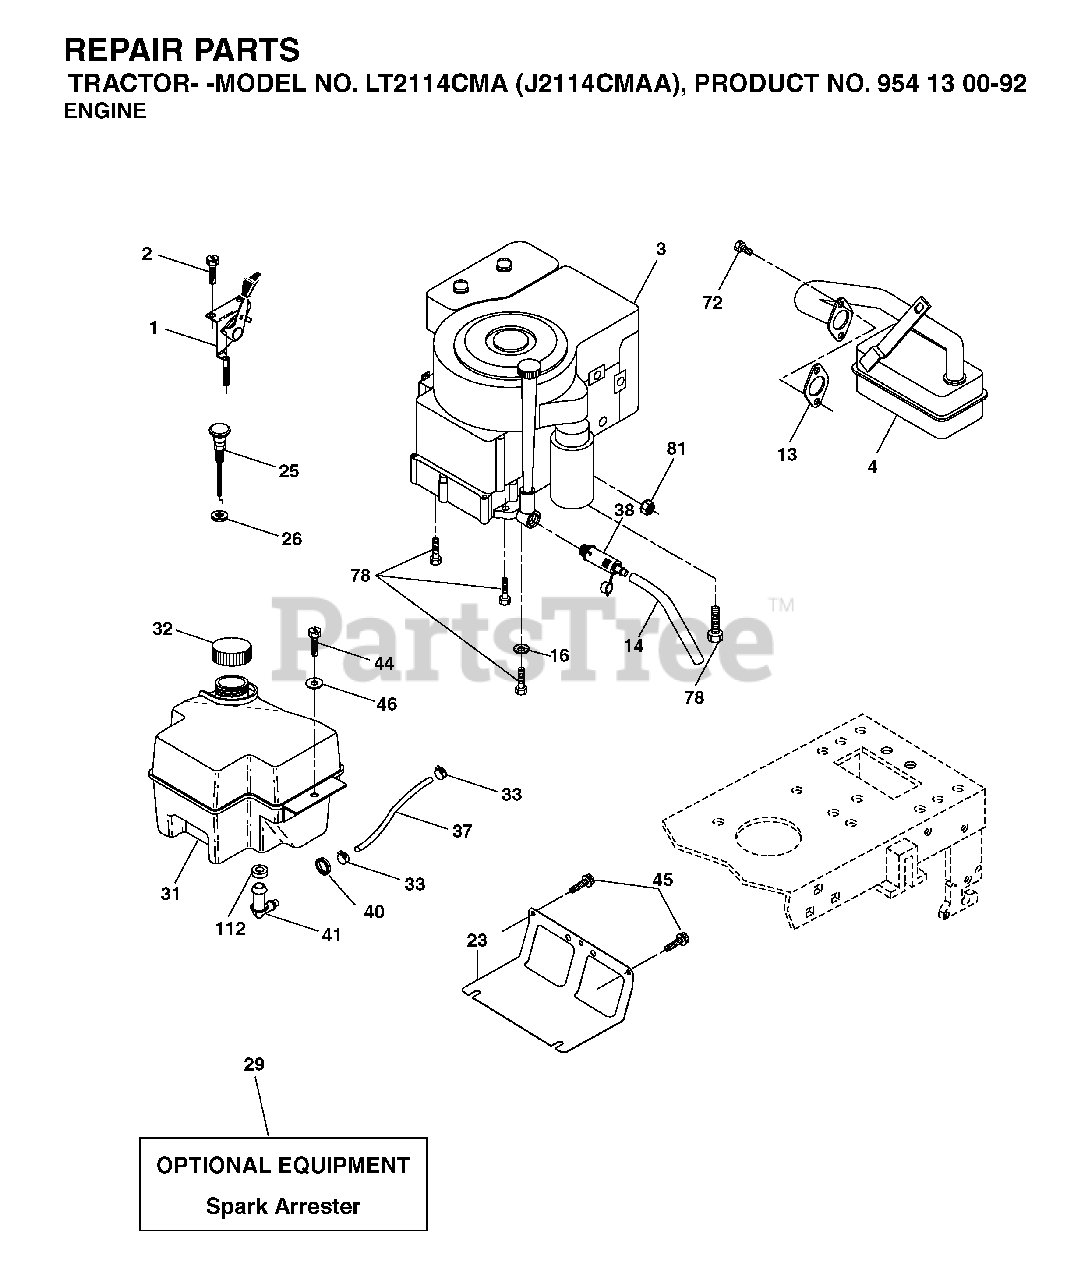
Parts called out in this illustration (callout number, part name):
1	CONTROL TH/CH FLAG
2	SCREW
13	REPL BY 532 27 22-93
14	TUBE, DRAIN OIL ASM.
16	LOCKWASHER
23	SHEILD.BROWNING.DBR.GUARD
26	NUT KEPS 3/8 - 24 UNF
29	ARRESTER SPARK (OPTIONAL)
31	GAS TANK 2GAL
32	FUEL CAP
33	HOSE CLAMP
37	LINE.FUEL.20
38	PLUG DRAIN OIL EASY
40	GROMMET T
41	STEM FUEL TANK
44	SCREW HEXWSHR 1/4-20X3/4
45	SCREW, 3/8-16X3/4
62	LOCKWASHER
72	SCREW
78	SCREW.3/8-16
81	NUT
112	BUSHING OUTLET T
